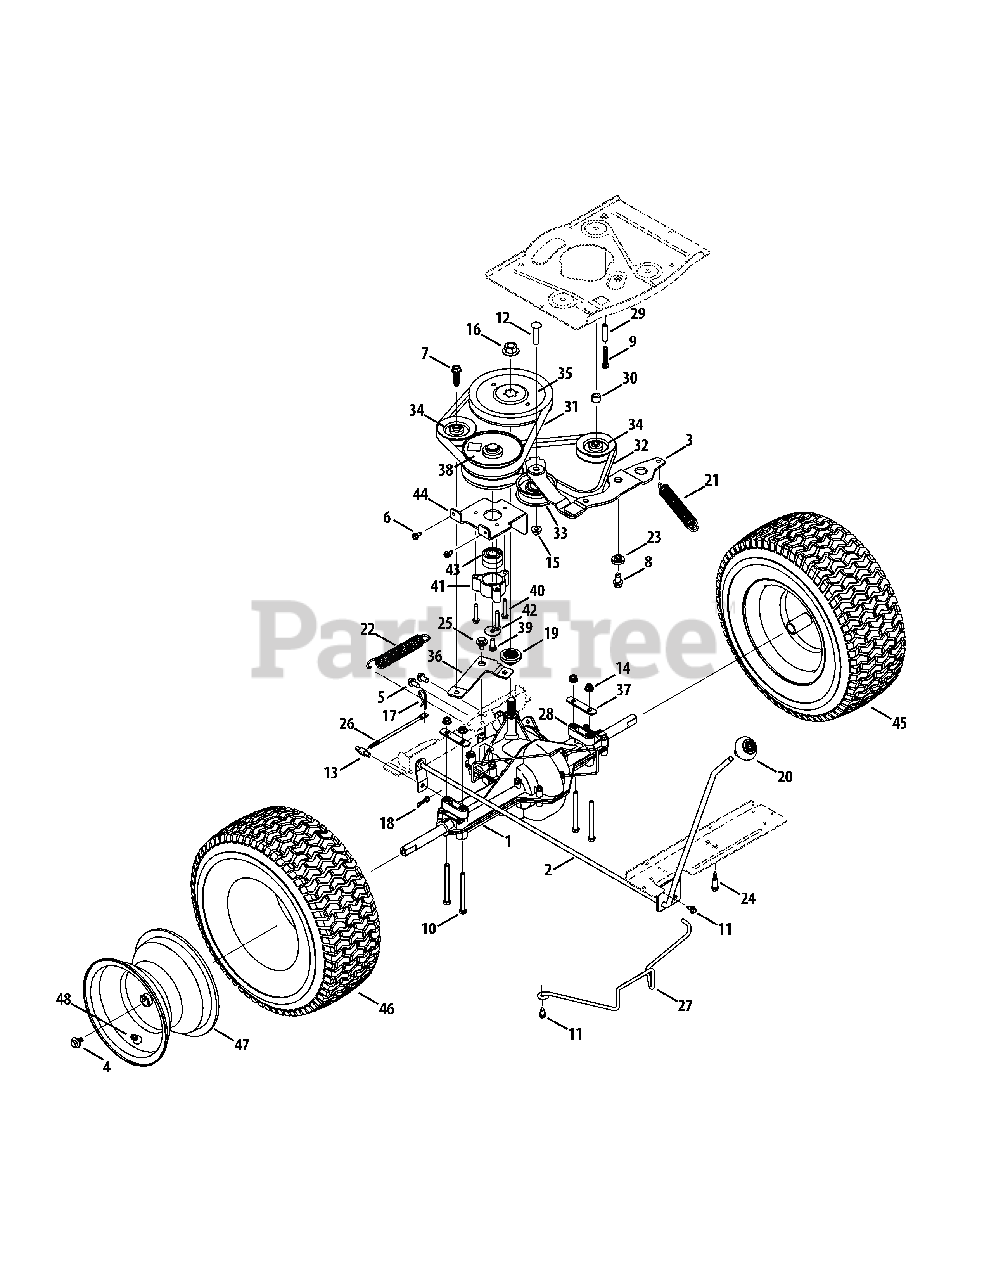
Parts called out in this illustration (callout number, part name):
1	Transmission Assembly
2	Shift Handle Assembly
3	Drive Assembly Idler
4	Screw, 5/16-24 x .750
5	Tap Screw, 5/16-18, .750
6	Tap Scew, 1/4-20, 0.500
7	Screw, 3/8-16 x 1.375
8	Tap Screw, 3/8-16, 0.750
9	Screw, 1/4-20 x 1.750
10	Hex Cap Screw, 5/16-18 x 3.5, Gr5
11	Tap Screw, 1/4-20 x .625
12	Screw, Carriage: 3/8-16 x 1.75"
13	Adjustable Ferrule, 1/4-20 X 1.00
14	Flange Locknut, 5/16-18
15	Flange Lock Nut, 3/8-16
16	Flange Nut, 9/16-18
17	Internal Cotter Pin, .125 Dia.
18	Bow-Tie Cotter Pin
19	Pulley Hub, 5/8 Spline
20	Shift Knob
21	Extension Spring, .94 Dia. X 6.74 Lg.
22	Extension Spring, .97 OD X 6.18
23	Shoulder Spacer, 1.00 X .38 X .38
24	Shoulder Screw, .368 x .75, 1/4-20
25	Shoulder Screw, .560 x .165, 5/16-18
26	Shift Rod
27	Deck Belt Keeper, 30"
28	Spacer
29	Spacer, .260 X .372 X 1.420
30	Spacer, .385 x .625 x .500
31	V-Belt, 5L:35.25
32	V-Belt, 5L:35.28
33	Flat Idler Pulley, 2.75 OD
34	V-Type Idler Pulley, 3.06
35	V-Type Pulley, 6.56
36	Rear Idler Arm Bracket
37	Transaxle Mounting Bracket
38	Variable Speed Pulley Assembly
39	Hex Head Lock Screw, 5/16-24:.750
40	Tap Screw, 1/4-20:1.500
41	Bearing Cup
42	Flat Washer, .330x1.250x.060
43	Ball Bearing, 17 X 40 X 12
44	Variable Bracket
45	Complete Wheel Assembly
46	Tire, 16 x 6.5 x 8 Sq. Shldr.
47	Rim Assembly, 8.0 x 5.38
48	Air Valve
